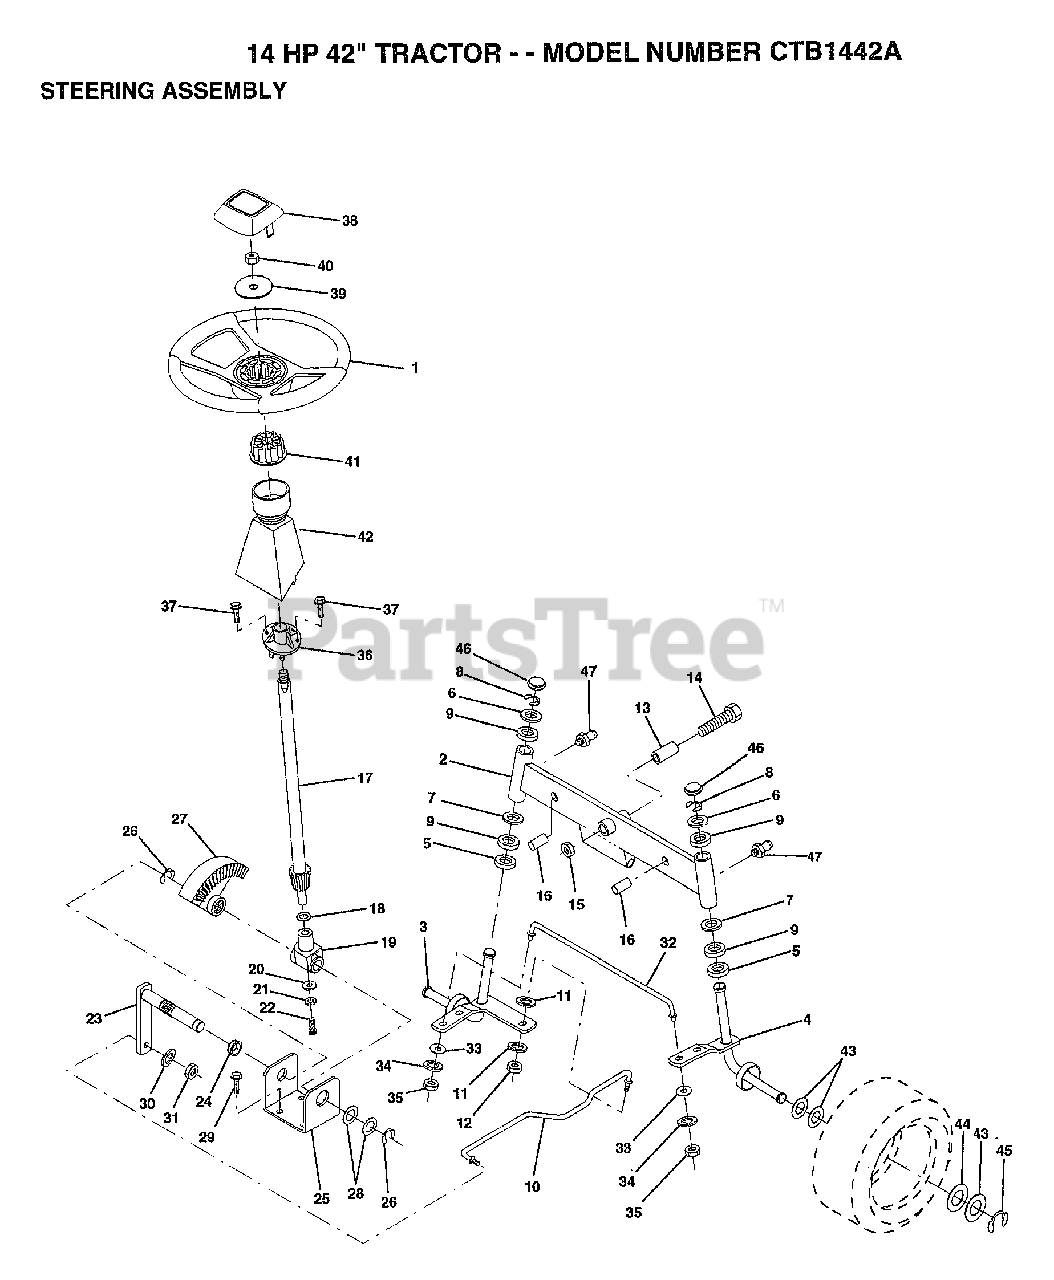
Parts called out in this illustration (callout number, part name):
3	SPINDLE LH
4	SPINDLE RH
5	WASHER .T
6	WASHER
7	WASHER
8	RING
9	COL. SRTG. BEAR.
11	LOCKWASHER
13	BEARING
14	BOLT HEX 5/8-11
15	"NUT-LOC,FLANGE LT"
16	AXLE PIN
17	SHAFT ASM
18	THRUST WASHER
19	SUPPORT.SHAFT
21	LOCKWASHER
22	"SCREW,SPECIAL"
24	NYLINER T
25	"BRKT,STEERING"
26	RING
27	GEAR SECTOR
28	WASHER .T
29	SCREW
30	LOCKWASHER
32	TIE ROD
33	WASHER M
34	LOCKWASHER
35	NUT.LOCK.5/16-24
38	ST WHL INSERT CAP
39	WASHER T
40	GRIPCO NUT
41	ADAPTER-WHEEL LT
42	"TUBE, STR SHAFT"
43	WASHER
44	WASHER
45	RING
46	CAP
47	ZERK M
56	WASHER
